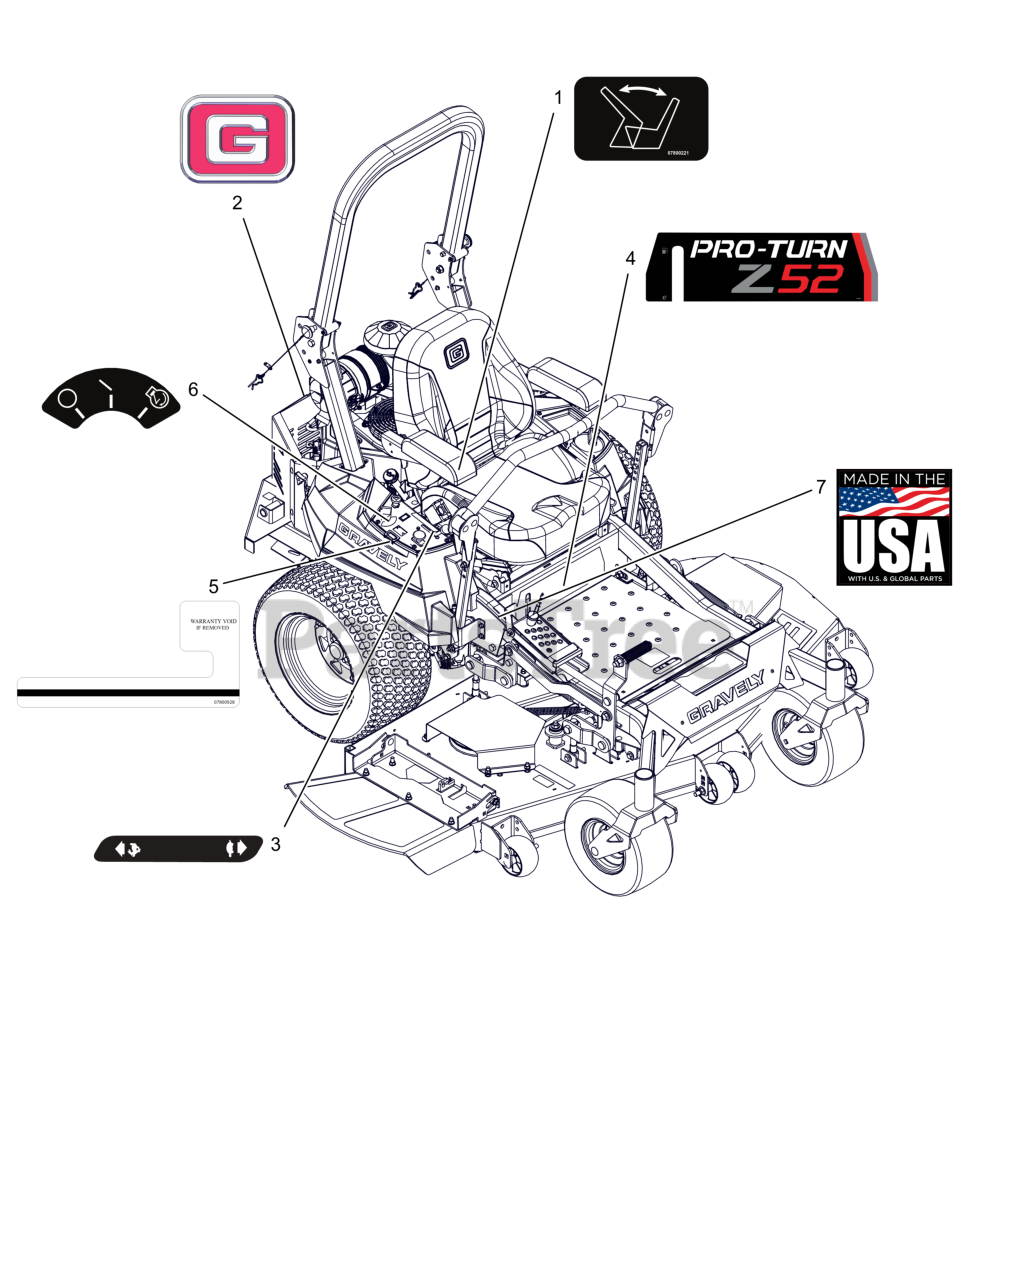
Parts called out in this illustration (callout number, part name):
1	DECAL - SEAT RELEASE
2	DECAL, GRAVELY BRAND
3	DECAL, DASH DECAL
4	DECAL, PRO-TURN Z52
5	DECAL,HOURMETER - SECURITY
6	DECAL, KEYSWITCH
7	DECAL, MADE IN USA
